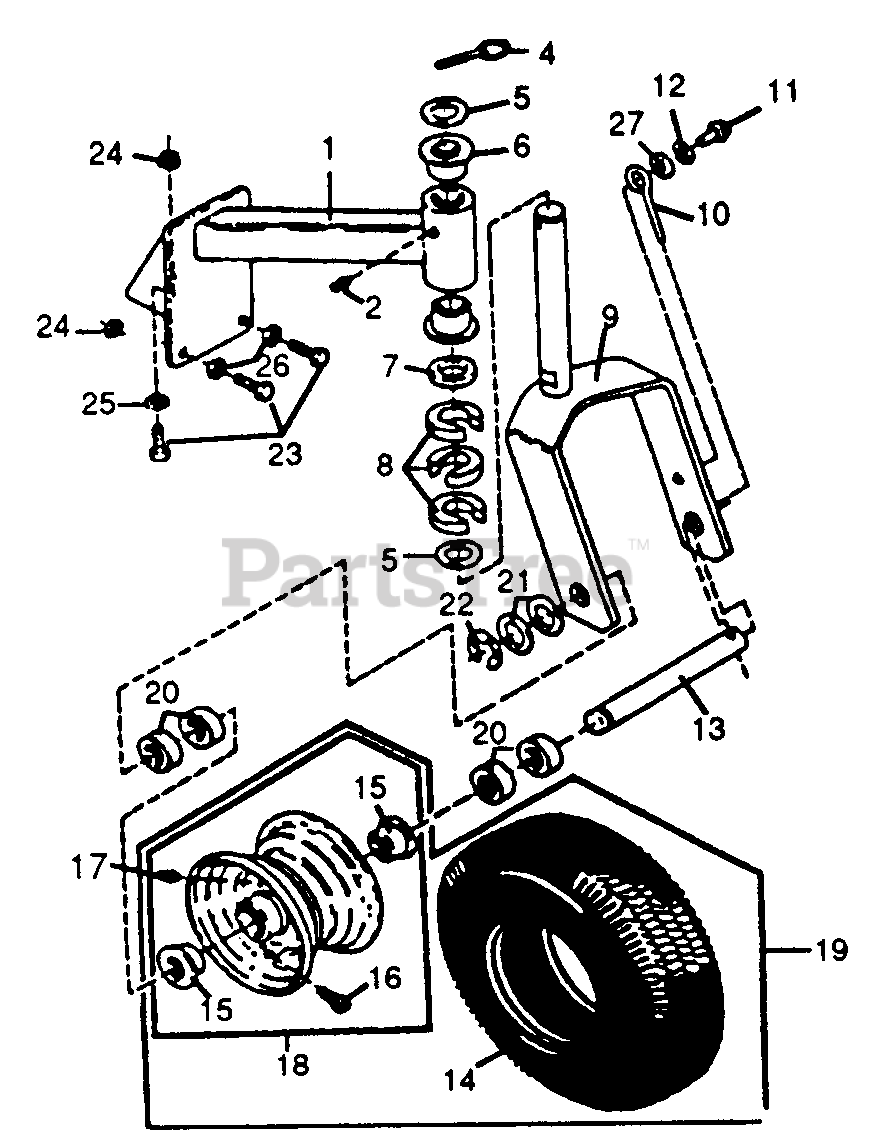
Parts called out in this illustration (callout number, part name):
1	Mount Bracket, Turf Caster
2	Zerk Fitting
4	Pin, Caster Post
5	Machinery Bushing, 1"
6	Bushing, Caster Tube
7	Spacer
8	Spacer, CasterTube
9	Yoke, Turf Caster
11	3/8" - 16 x 3/4- Hex Hd Cap Screw
12	3/8" Flat Washer
13	Shaft, Caster Wheel
15	Ball Bearing
16	Valve Stem
17	Zerk Fitbng
18	Rim Assembly
19	Wheel Assembly, Pneumatic
20	Spacer
21	3/4 Machinery Bushing
22	3/4 E-Ring
23	5/16 - 18 x 3/4 Hex HdCap Screw
24	5/16 -18 Flange Nut
25	5/16 Flat Washer
26	5/16- Lock Washer
27	3/8 Lock Washer
